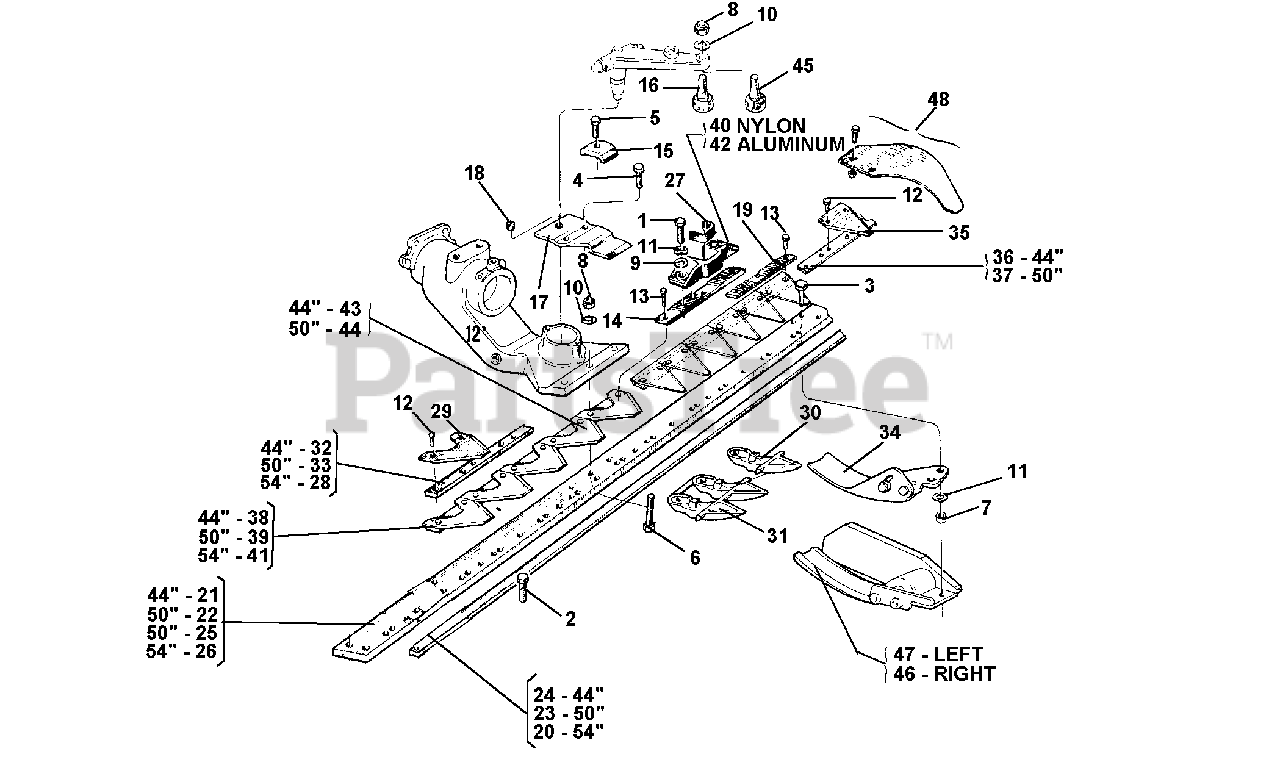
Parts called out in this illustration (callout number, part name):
1	SCREW M8 X 16
2	SCREW TE M10 X 25
3	SCREW M8 X 25
4	SCREW M10 X 30
5	SCREW TE M10 X 35 UNI 5739-8G
9	WASHER, FLAT 8.4
10	SUPER WASHER 10 DIN 6796
11	WASHER, LOCK 8.4
12	RIVET 5.3 X 14
13	RIVET TSV 5.3 X 14
14	SUPPORT, BLADE CONNECTION
15	HOLDER, STRIP
16	BLADE CONTROL PIN
17	HOLDER, BLADE, MULCHING
18	SCREW, HEADLESS M16 X 12
19	BLADE PLATE
20	19 SECTIONS BLADE GUIDE
21	BAR, CENTRAL, 1.10
22	BAR, CENTRAL, 1.27
23	GUIDE, BLADE L 1270
24	GUIDE, BLADE, 15 SECTIONS
25	HEAVY FRONT BAR 1.27 MT.
26	FRONT BAR 1.40 MT.
28	STRIP, FOR 19-SECTION BLADE
29	SECTION, SCORED BLADE
30	FINGER, SINGLE
31	TOOTH, DOUBLE MULCHING
32	STRIP, 15 SEC. BLADE
33	STRIP, 17 SEC. BLADE
34	SKID, INTERMEDIATE
35	SECTION OF LONG SCORED BLADE
36	STRIP WITH 22 SECTIONS
37	STRIP WITH 25 SECTIONS
38	BLADE, 15 SECTIONS
39	BLADE, 17 SECTIONS
40	NYLON BLADE COUPLING
41	BLADE 19 SECTIONS
42	BLADE CONNECTION
43	BLADE WITH 22 NARROW SECTIONS
44	BLADE WITH 25 NARROW SECTIONS
45	BALL BEARING PIN
46	RIGHT SLEDGE
47	LEFT SLEDGE
48	CUTTER BAR SIDE PROTECTION
